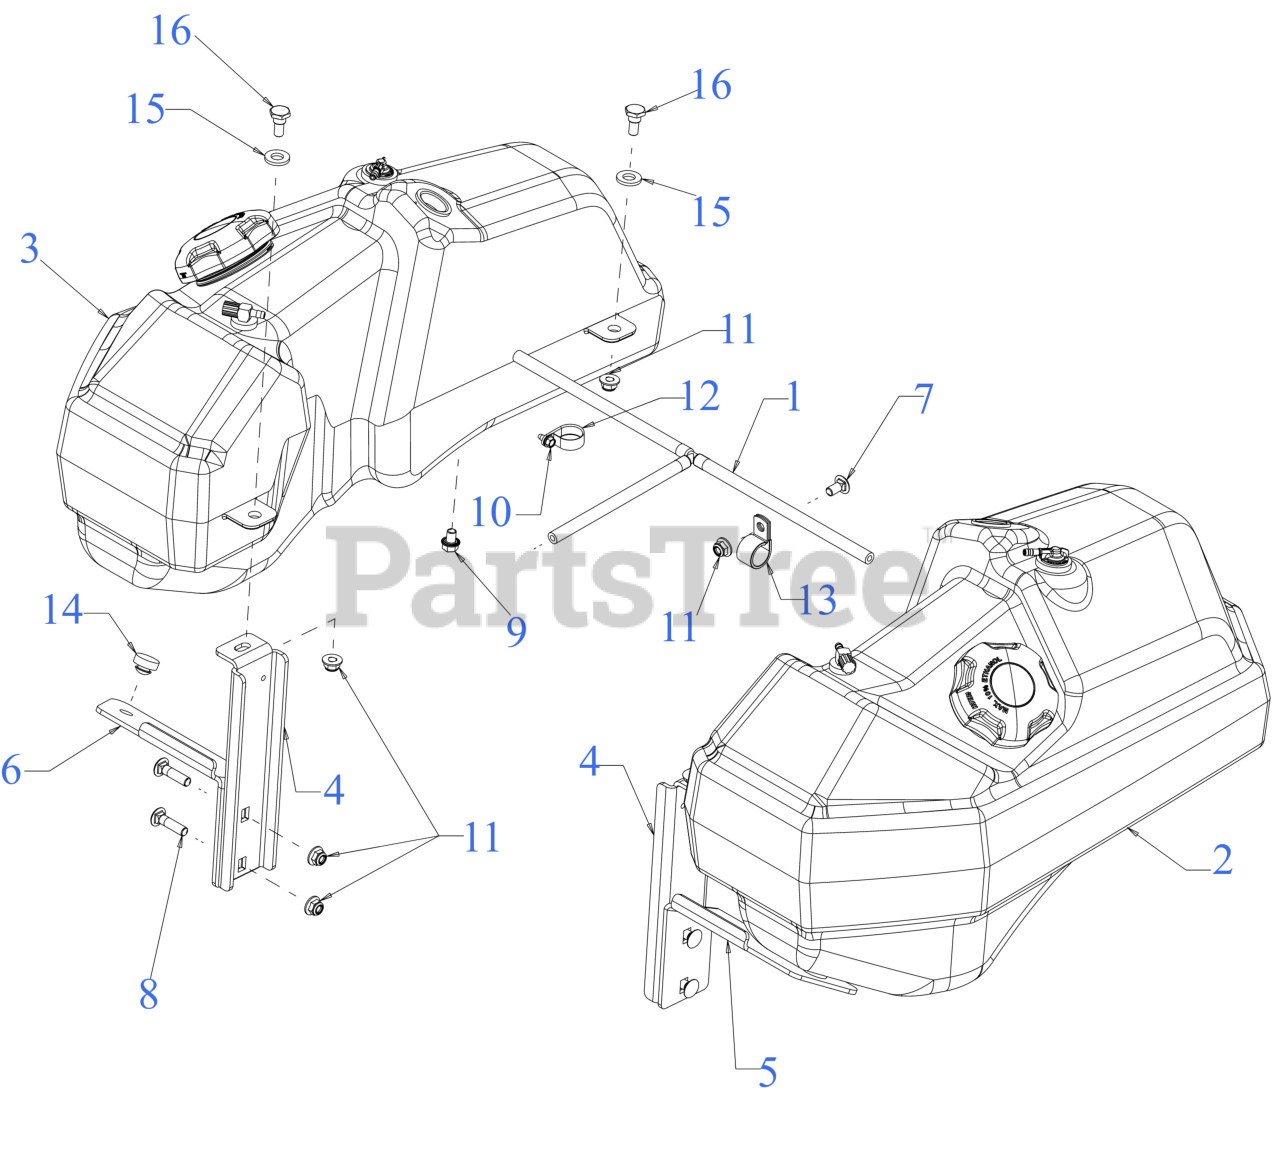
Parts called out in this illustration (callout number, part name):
1	FUEL LINE ASSEMBLY
2	FUEL TANK (RH) (7.25)
3	FUEL TANK (LH) (7.25)
4	FUEL TANK MOUNTING BRACKET
7	CARRIAGE BOLT 3/8-16 x .750 GR5
8	CARRIAGE BOLT 3/8-16 x 1.50
9	SCREW 3/8-16 x .500 GR5
10	SCREW 1/4-20 X.500
12	DRAIN HOSE CLAMP
13	HOSE CLAMP 1.0"
14	RUBBER BUMPER 1.000 x .313
15	FLAT WASHER .510 x 1.000 x .125
16	SHOULDER SCREW .498 DIA x .340
